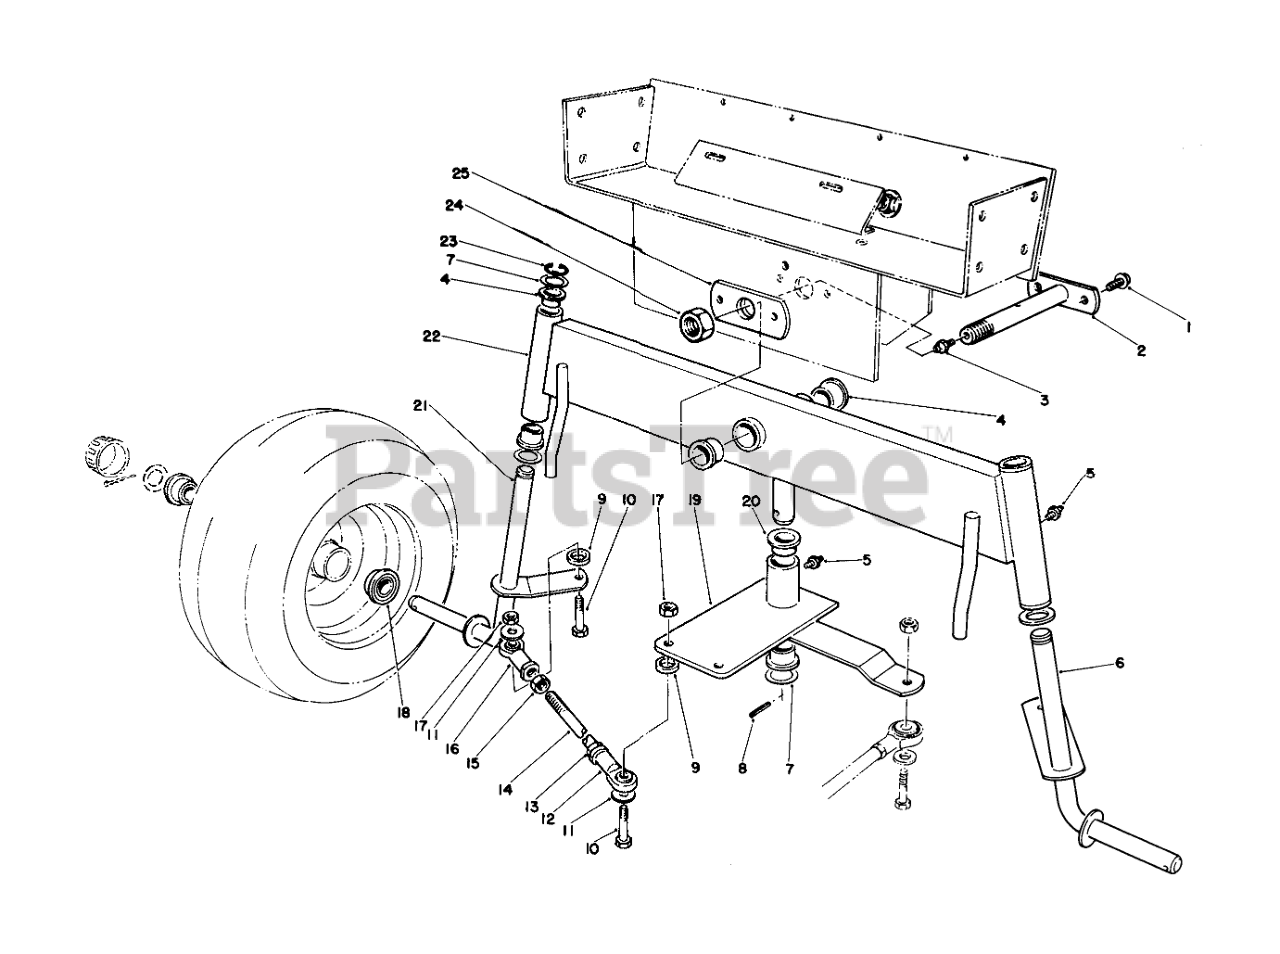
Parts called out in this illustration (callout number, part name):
1	SCREW-HHFTF
2	Axle-Pivot
3	FITTING-GREASE
4	BUSHING PM
5	GREASE FITTING
6	Spindle LH.
7	WASHER-THRUST
8	PIN-SPRING
9	WASHER
10	SCREW-HH
11	WASHER-FLAT
12	BALL JOINT LH
14	TIE ROD - STEERING
15	NUT-JAM
16	BALL JOINT RH
17	NUT-HEX
18	Bearing
19	Pivot Plate (Incl. Ref. No-s. 5 & 20)
20	BEARING-FLANGE
21	Spindle R.H.
22	Rear Axle (Incl. Ref. No-s. 4-5)
23	E-RING
24	NUT-LOCK NI
25	CHANNEL PLATE
